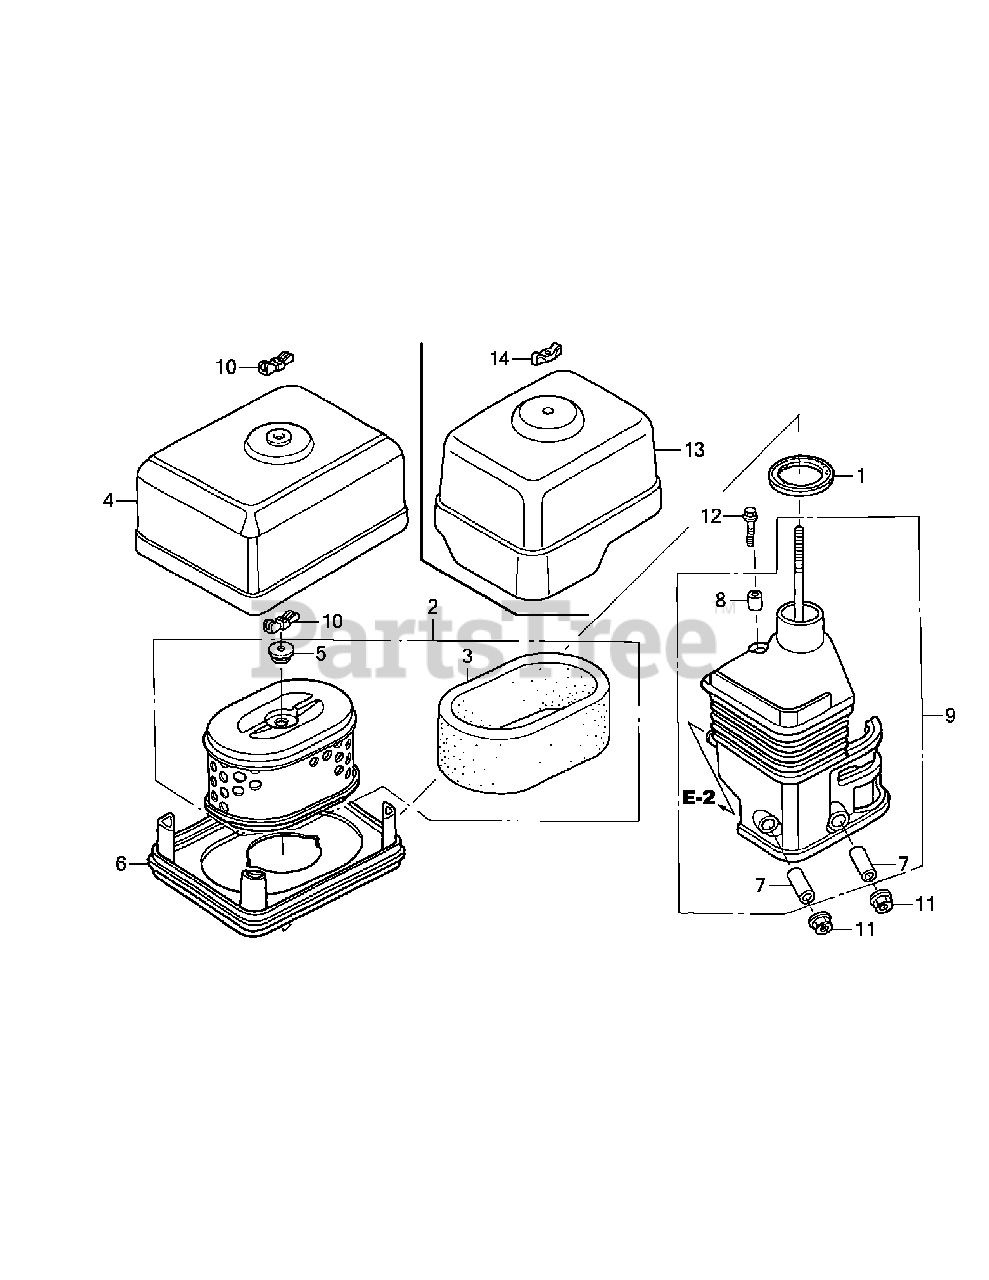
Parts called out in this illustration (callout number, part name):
1	Packing, Elbow
2	Element, Air Cleaner(Dual)
3	Filter, Outer
4	Cover, Air Cleaner(Dual)
5	Grommet, Air Cleaner
6	Nose, Silencer
7	Collar, Air Cleaner
8	Collar B, Air Cleaner
9	Elbow Comp., Air Cleaner
10	Nut, Tool Box Setting
11	Nut, Flange, 6Mm
12	Bolt, Flange, 6X20
13	Cover, Air Cleaner
14	Nut, Air Cleaner
